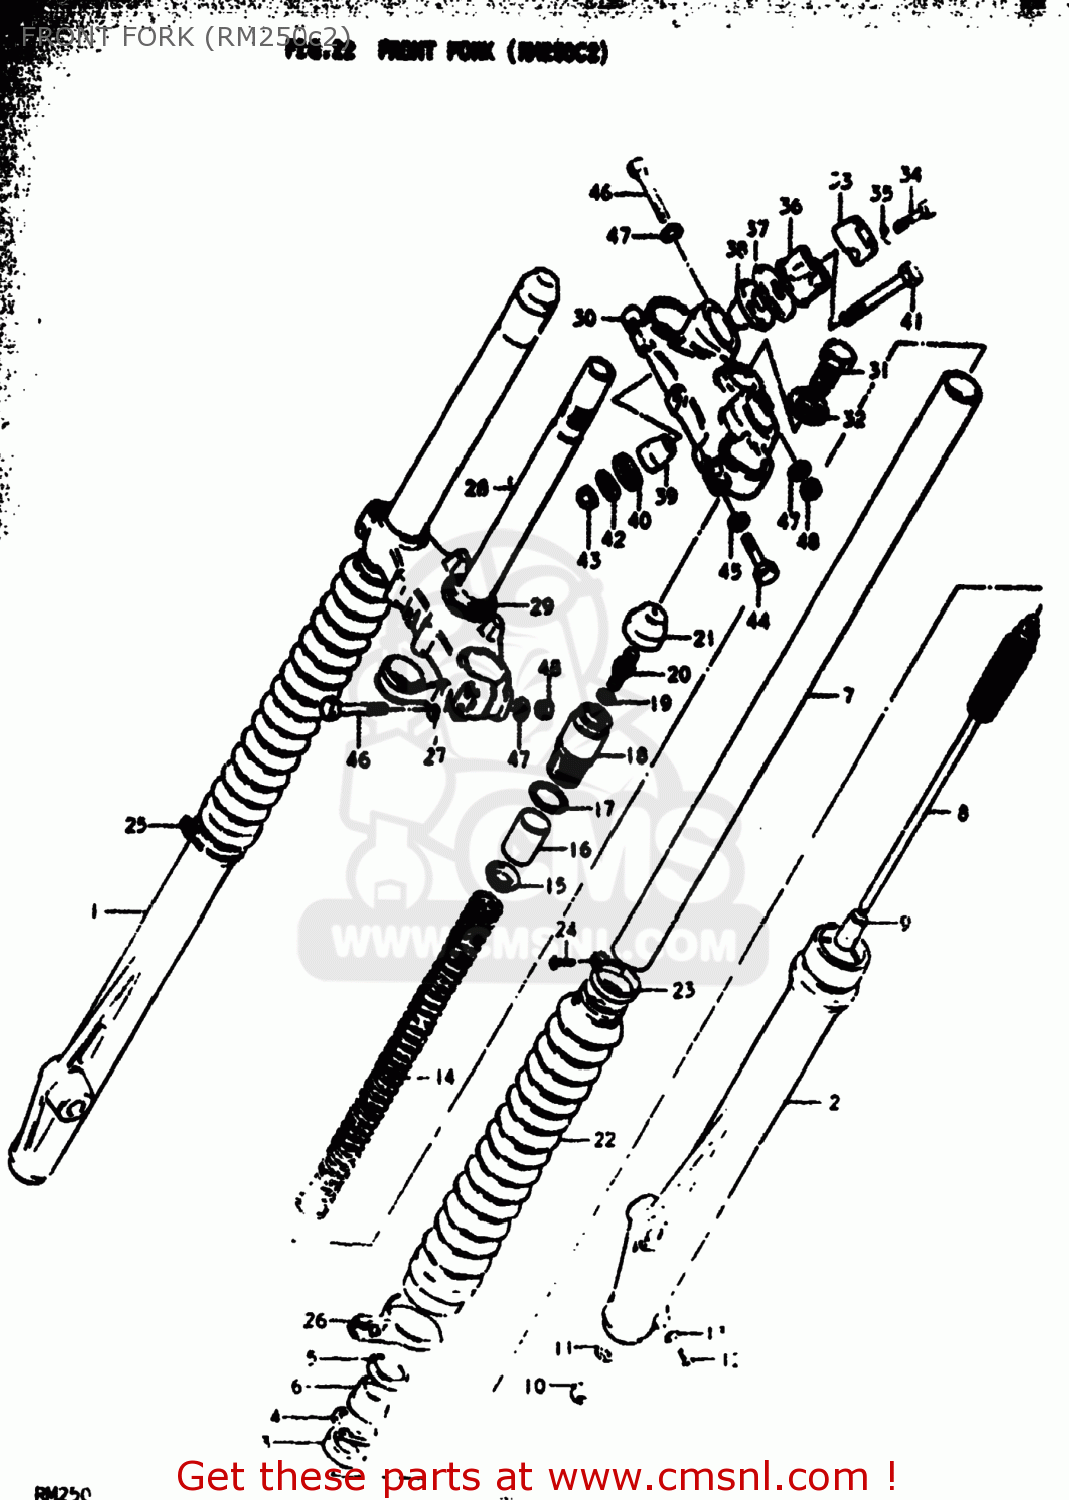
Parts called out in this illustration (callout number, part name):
1	TUBE,OUTER,RIGHT
2	TUBE,OUTER,LEFT
3	OIL SEAL,FRONT FORK
4	CIRCLIP,FORK OIL SEAL
5	GUIDE.FORK DUST
6	DUST SEAL,FRONT FORK
7	TUBE,FORK,INNER
8	CYLINDER,FRONT FORK
9	PIECE,OIL LOCK
10	BOLT,FORK CYLINDER(10X25)
11	GASKET (NAS)
12	SCREW
13	GASKET,DRAIN,PLUG (NAS)
14	SPRING
15	GUIDE,FRONT FORK SPRING C
16	SPACER,SPRING
17	O RING
18	CAP ASSEMBLY,FORK
19	O RING
20	VALVE
21	CAP
22	BOOT
23	BAND,BOOT
24	SCREW
25	BAND,FRONT FORK COVER
26	BAND,FRONT FORK COVER
27	GUIDE,CABLE
28	STEM,STEERING
29	RACE,STEERING OUTER LWR
30	HEAD,STEERING STEM
31	BOLT
32	WASHER
33	HOLDER,HANDLEBAR
34	BOLT
35	LOCK WASHER
36	HOLDER,HANDLEBAR
37	COVER, UPPER
38	CUSHION
39	RUBBER, LOWER
40	SPACER,STEERING DAMPER
41	BOLT,HANDLE HOLDER
42	WASHER
43	NUT 12MM
44	BOLT
45	LOCK WASHER
46	BOLT 8X55
47	WASHER
48	NUT
